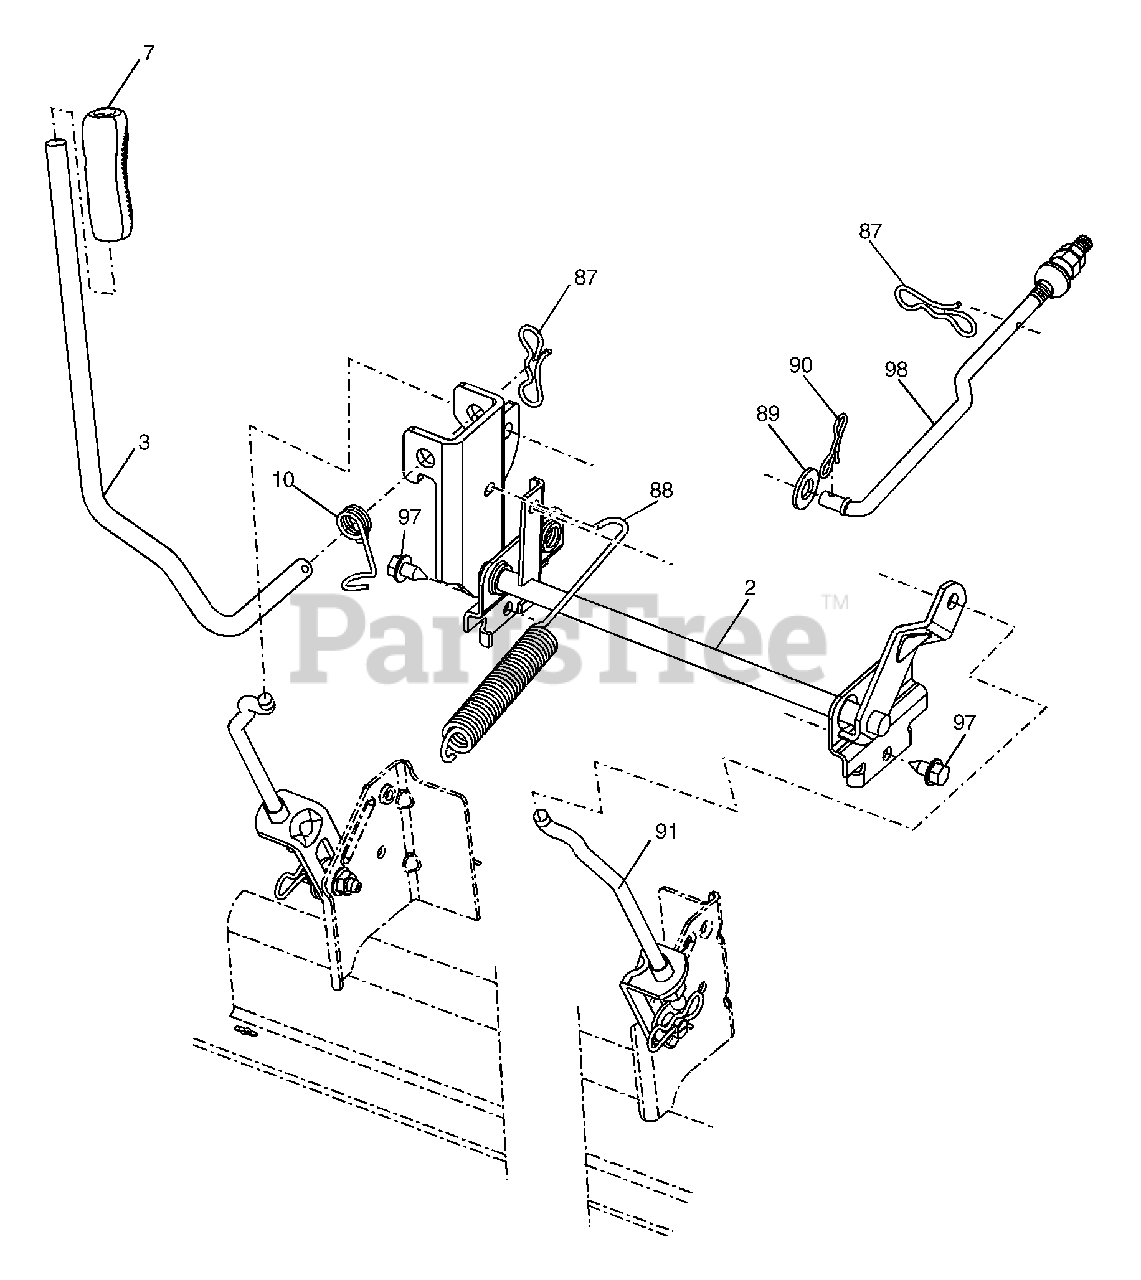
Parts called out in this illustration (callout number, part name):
2	Shaft Asm., Lift
3	Lever Asm., Lift Rh
7	Grip, Lever
10	Spring Torsion
87	Pin Cotter 7/16 Bow Tie Lock
88	Spring Lift Assist
89	Washer Clear Zinc
90	Pin Cotter 5/16 Bow Tie Lock
91	Link Lift Susp Mower Rear
97	Screw 3/8-16 x .75 Smgml Tap/R.Z
98	Link Lift Susp. Front Mower
